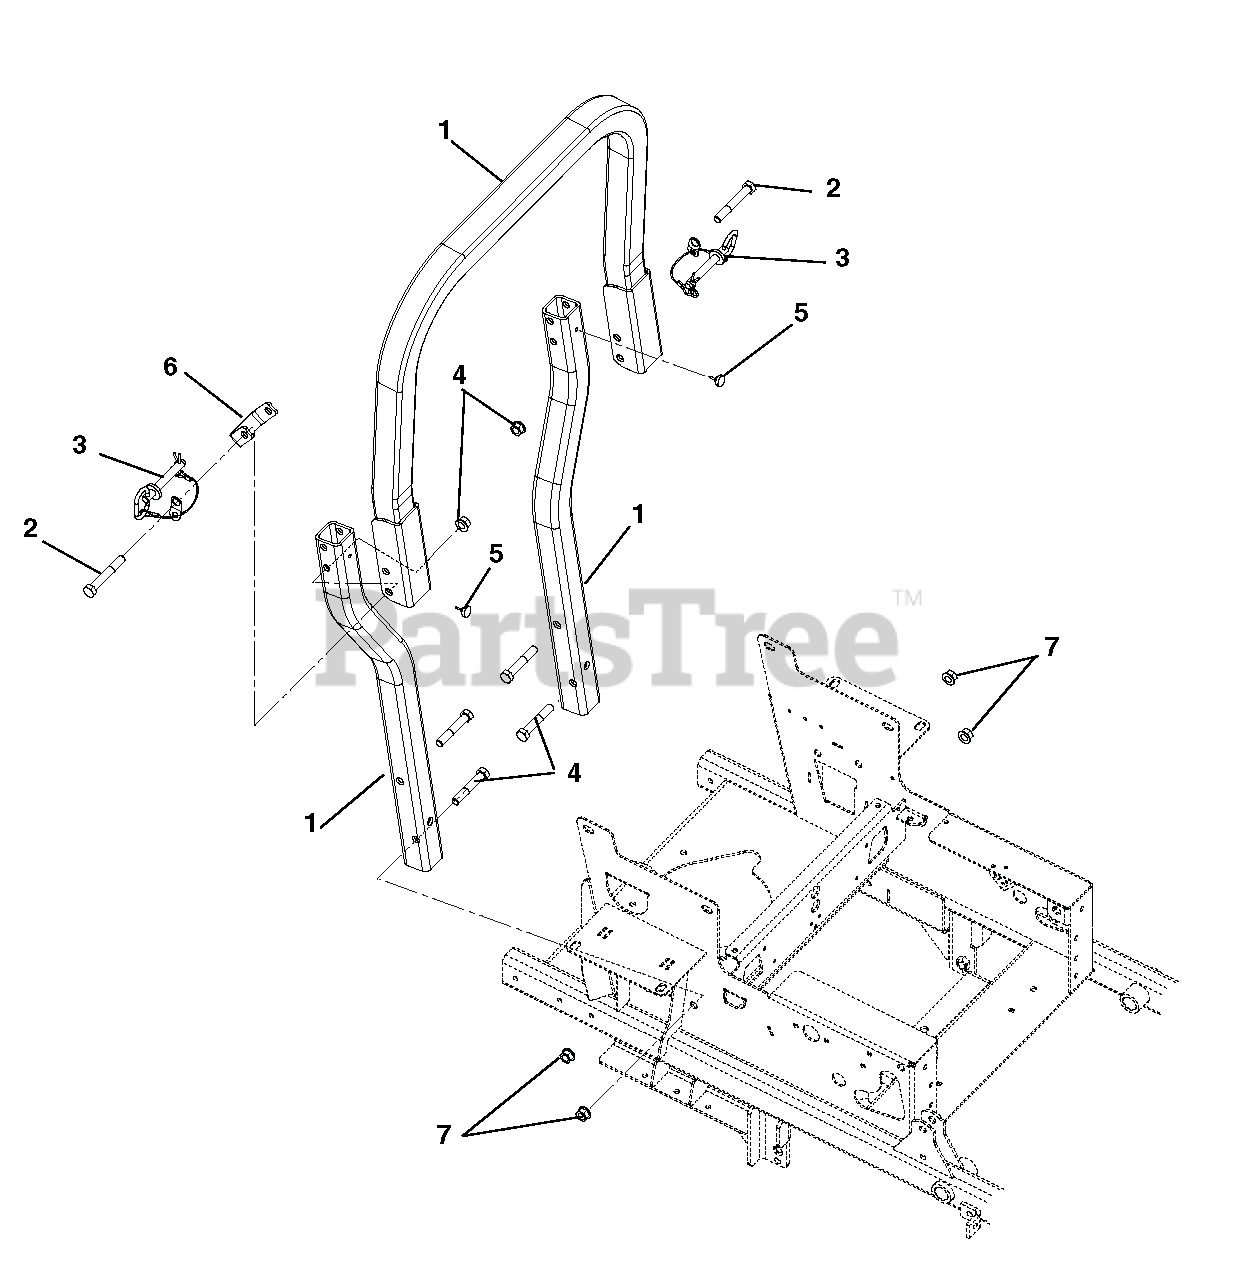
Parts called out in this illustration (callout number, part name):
1	ROPS, PT/PT100 REPLACEMENT
2	@BLT-HEX .50-13X3.50 GR5 YWZC
3	ASSY, ROPS PIN/LANYARD
4	@NUT-LK-TOP-FLG .50-13 YWZC
5	BUMPER, ROPS RUBBER
6	BRKT, ROPS STOP, PRO-TURN YZ
7	@BLT-HEX .50-13X3.00 GR5 YWZC
